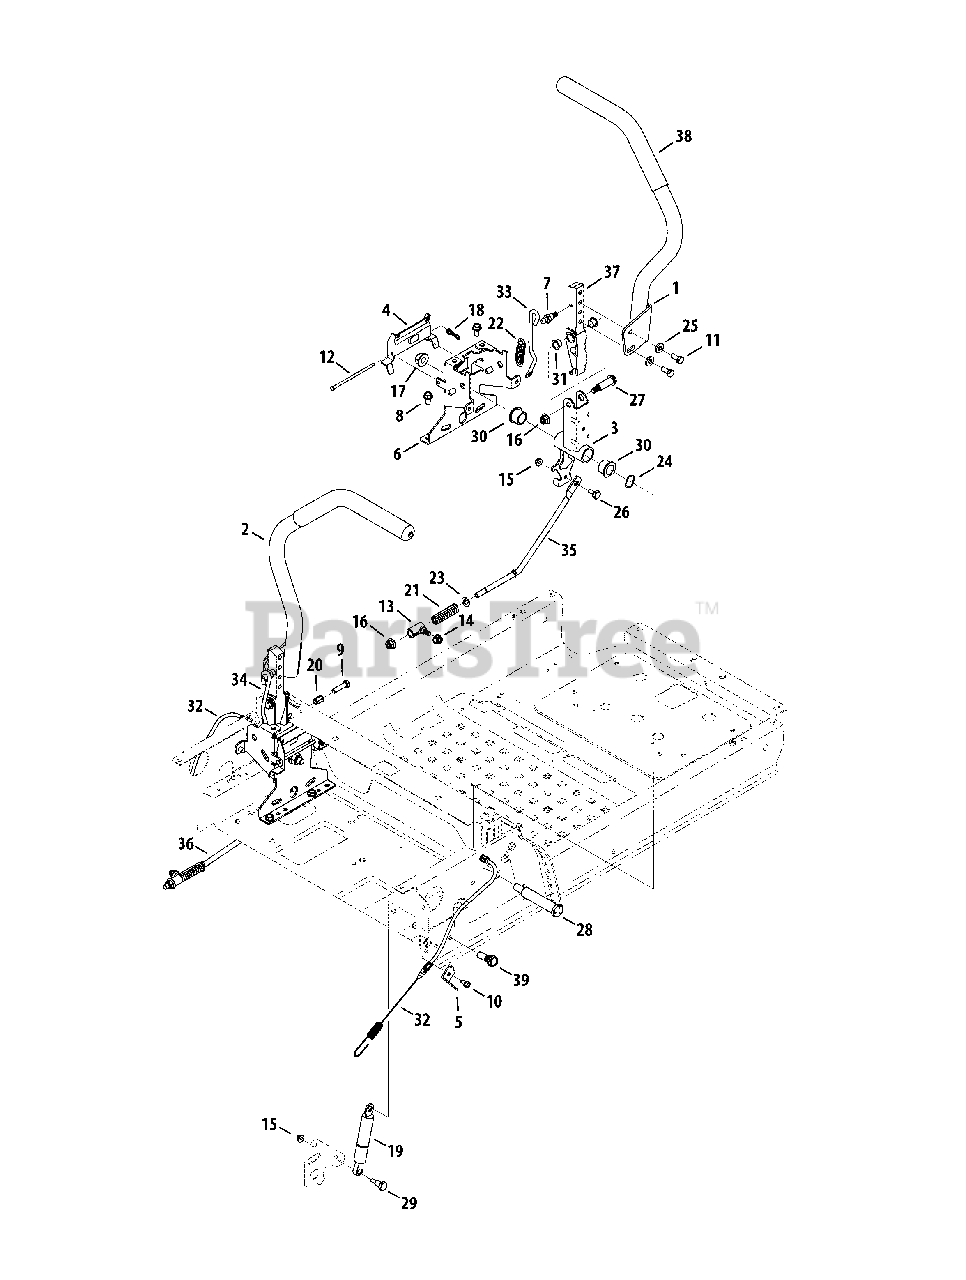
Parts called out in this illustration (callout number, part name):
1	ASSEMBLY, RH Lapbar Lever
2	ASSEMBLY, LH Lapbar Lever
3	BRACKET, Lapbar Pivot
4	ACTUATOR, Brake Lever
5	BRACKET, Brake Cable
6	BRACKET, Lapbar Pivot Support
7	SCREW, 5/16-18 X .48, Shoulder Ball
8	SCREW, 5/16-18 X .750, Hex Washer
9	SCREW, 5/16-18 X 1.25, Hex Cap
10	SCREW, Hex Head, 1/4-20 X 1/2
11	SCREW, 5/16-18 X .75, Hex Head Patch
12	PIN, .188 X 4.1
13	FERRULE, 3/8 ID X .420, Shoulder
14	NUT, 5/8-18 Hex Flange
15	NUT, Nylock Flanged, 1/4-20
16	NUT, 3/8-16, Flanged Lock, GR5, Zinc/Clear
17	NUT, 1/2-13, Flange Lock
18	PIN, 1/4-5/16, Bow Tie Cotter
19	DAMPENER, .87 OD X 7.06 LG
20	NUT, 5/16-18
21	SPRING, .45 X 3.215, Compression
22	SPRING, .56 X 2.31 X .105, Extension
23	WASHER, .385 X .62 X .063, Flat
24	WASHER, .785 X 1.0 X .012, Wave
25	WASHER, .344 X .750 X .120, Flat
26	SCREW, .375 DIA. X .181, Shoulder
27	SCREW, .498 DIA. X 1.296, Shoulder
28	SCREW, .75 X 3.25 X 1/2-13, Shoulder
29	SCREW, .395 DIA. X .56, Shoulder
30	BEARING, .75 X 1.00 X .73
31	BEARING, .500 X .627, Flange
32	CABLE, Park Prake
33	ROD, Lapbar Detent, RH
34	ROD, Lapbar Detent, LH
35	ROD, Hydro Control, RH
36	ROD, Hydro Control, LH
37	ARM, Lower
38	GRIP, Lapbar
39	SCREW, .395 DIA. X .83, Shoulder
